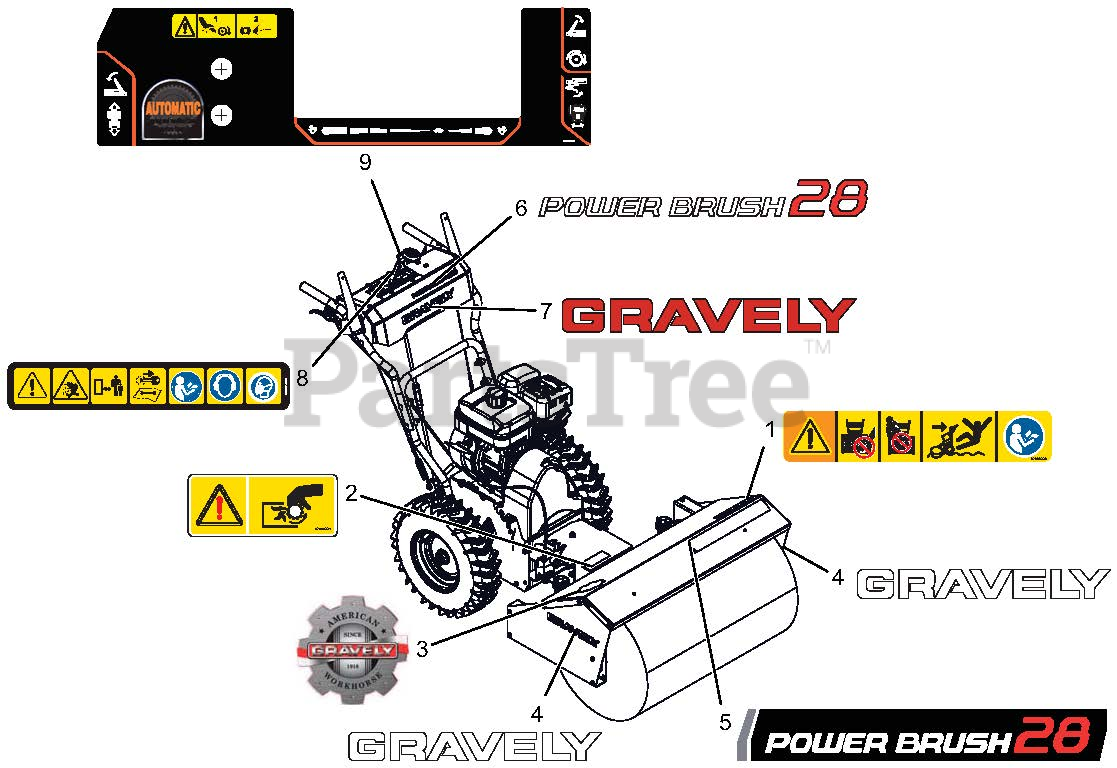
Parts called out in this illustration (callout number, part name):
1	DECAL, DANGER -POWER BRUSH-CE
2	DECAL, PTO WARNING
3	DECAL, GRAVELY HERITAGE-LARGE
4	DECAL, 9.5" GRAVELY LOGO
5	DECAL,POWER BRUSH 28,GRAVELY
6	DECAL,POWER BRUSH 28,GRAVELY
7	DECAL,GRAVELY,RED,9.5"
8	DECAL, SAFETY, DASH, BRUSH
9	DECAL,CONTROL,SMALL BRUSH
